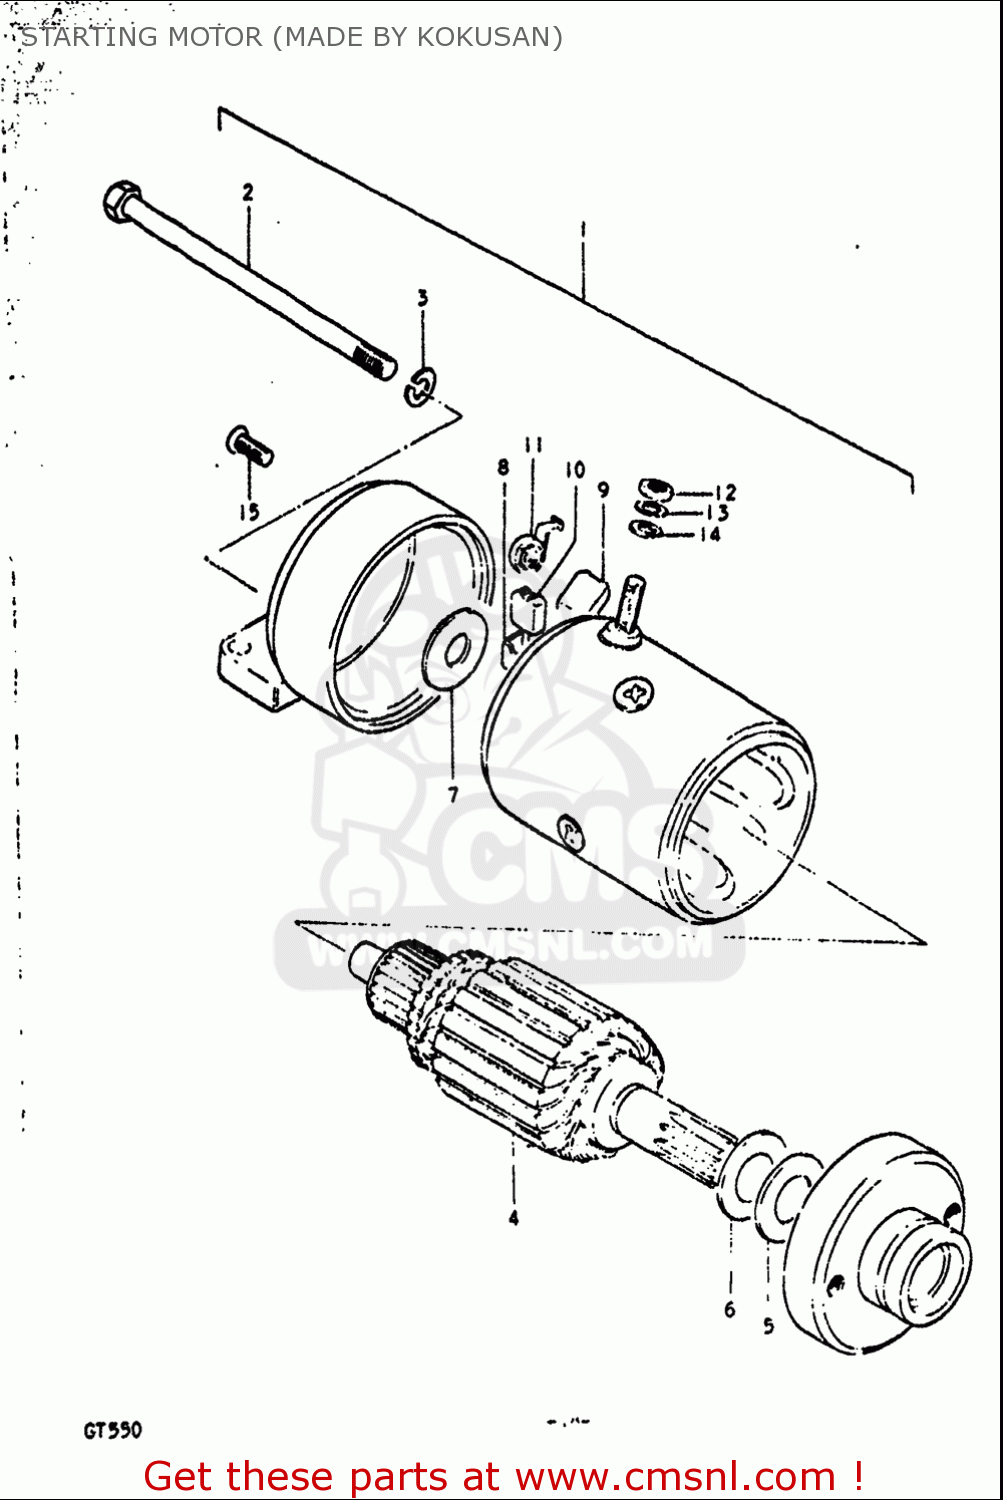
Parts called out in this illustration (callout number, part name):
3	WASHER,LOCK
9	BRUSH (+)
12	NUT
13	WASHER,LOCK
14	WASHER
15	SCREW
